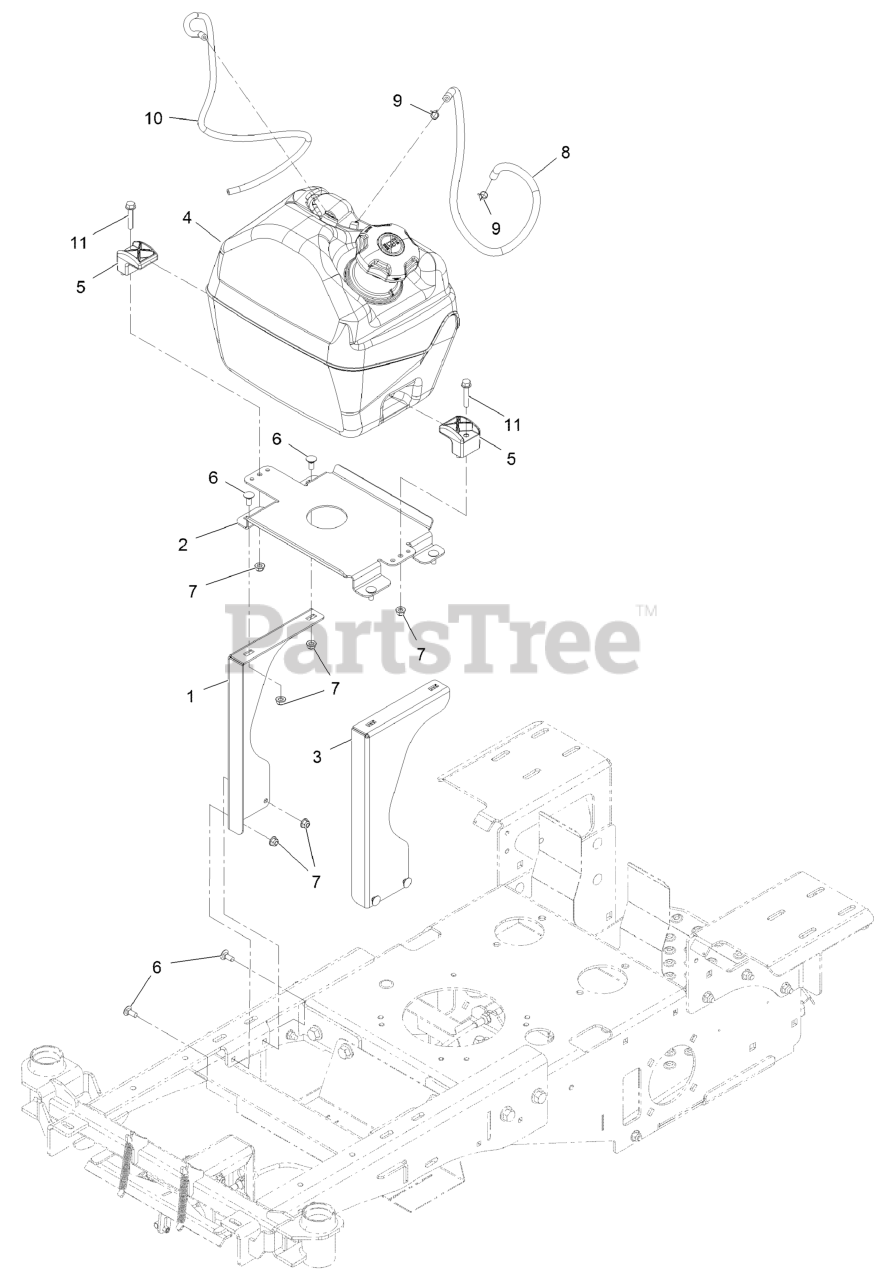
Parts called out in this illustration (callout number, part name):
1	PANEL, PLATFORM, FUEL TANK, JR36
2	SUPPORT-FUEL TANK
3	PANEL, PLATFORM, FUEL TANK, JR36, SS,.12
4	Fuel Tank ASM, 5 Gal
6	SCREW-CARR
7	Nut-Hex Flange
8	HOSE-FUEL
9	CLAMP-HOSE
10	HOSE-FUEL
11	Screw-HHF
